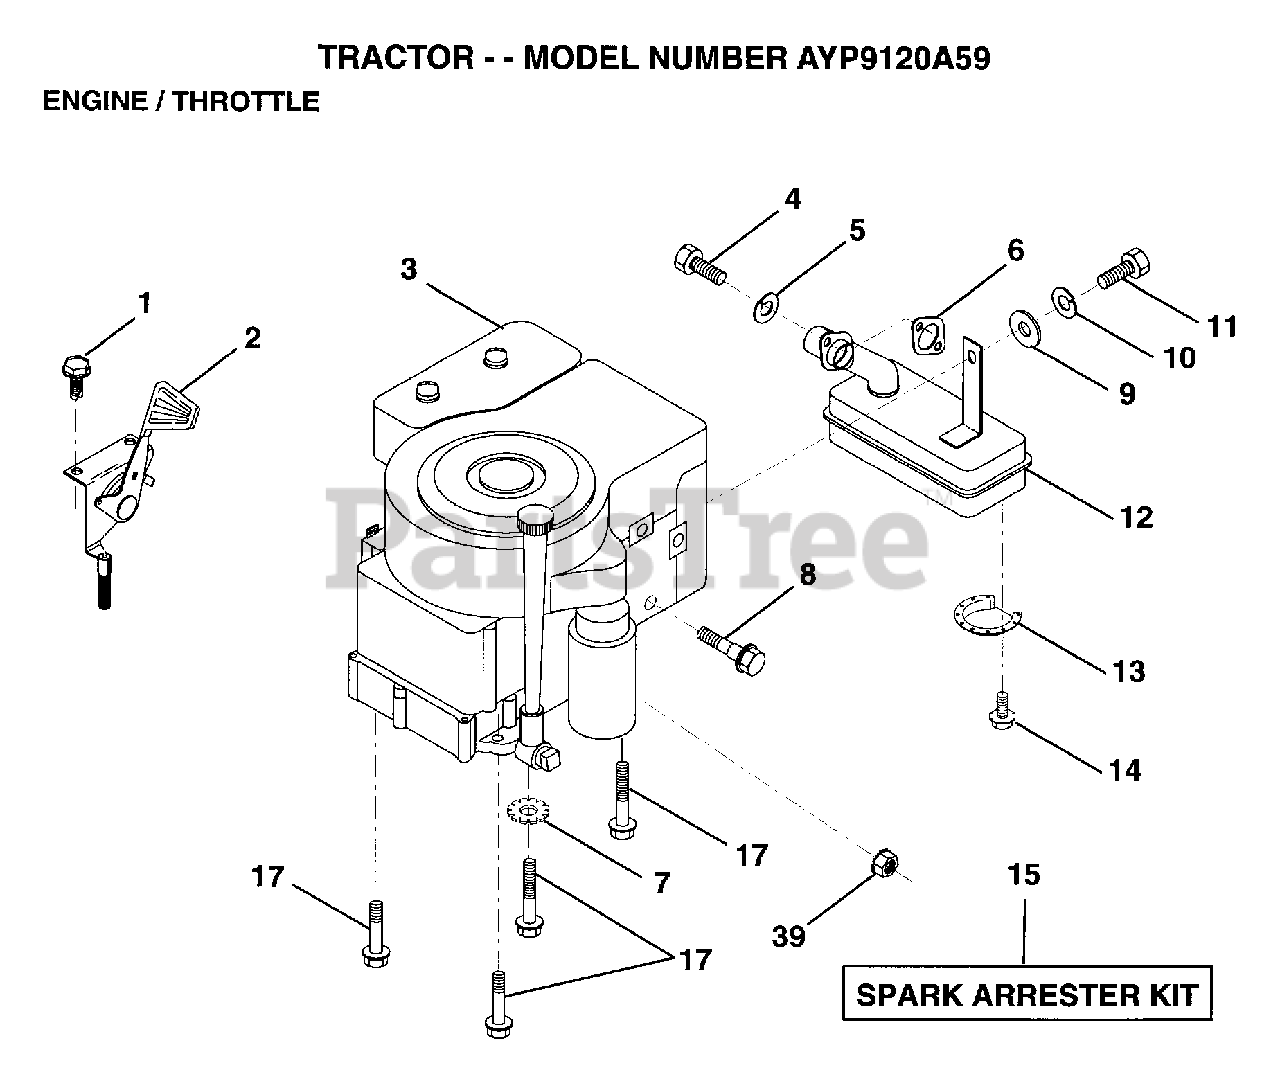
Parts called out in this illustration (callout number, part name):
1	SCREW.1/4-20X1/2
2	"CONTROL,THROTTLE"
4	SCREW
5	LOCKWASHER
7	LOCKWASHER
8	BOLT T
10	LOCKWASHER
12	MUFFLER
13	DEFLECTOR.222573
17	SCREW LT
18	"KEEPER,DR BELT GR"
39	NUT
